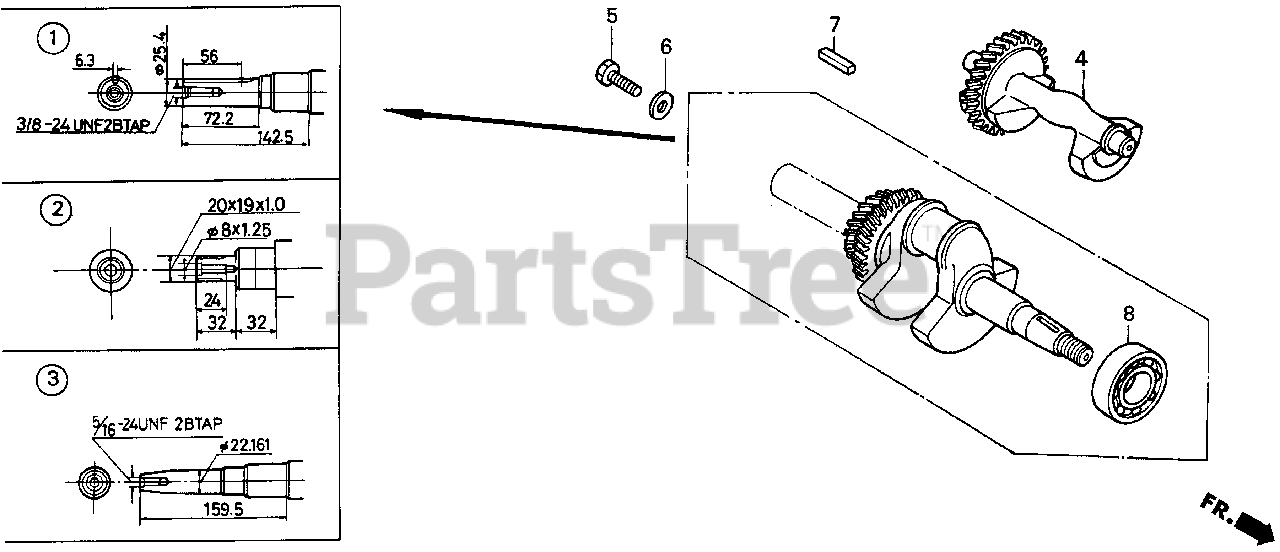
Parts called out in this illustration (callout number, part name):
3	CRANKSHAFT (V-TYPE)
4	WEIGHT, BALANCER
8	BEARING, RADIAL BALL (6207S)
